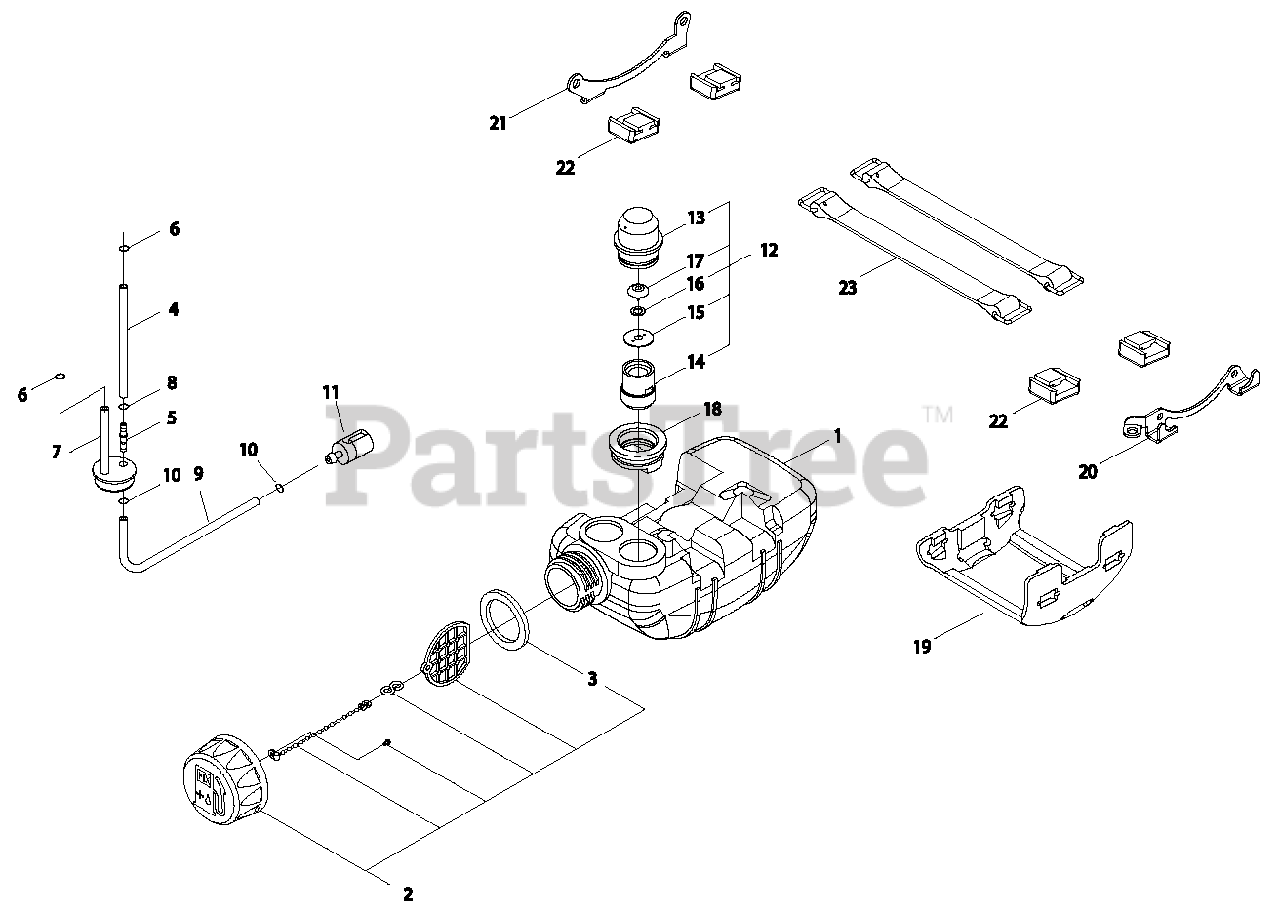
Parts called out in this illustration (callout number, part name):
1	TANK, FUEL
2	CAP ASSY - RED
3	GASKET, CAP
4	PIPE - FUEL
5	CONNECTOR, PIPE
6	CLIP - 6
7	GROMMET
8	CLIP - 6
9	PIPE - FUEL
10	CLIP - 6
11	FUEL FILTER ASSY
12	VENT ASSY
13	CAP, BREATHER
14	HOLDER, VENT
15	RETAINER
16	WASHER
17	VENT, FUEL TANK
18	GROMMET
19	GUARD, FUEL TANK
20	BRACKET - OUTER
21	BRACKET - INNER
22	CUSHION
23	STRAP, FUEL TANK
